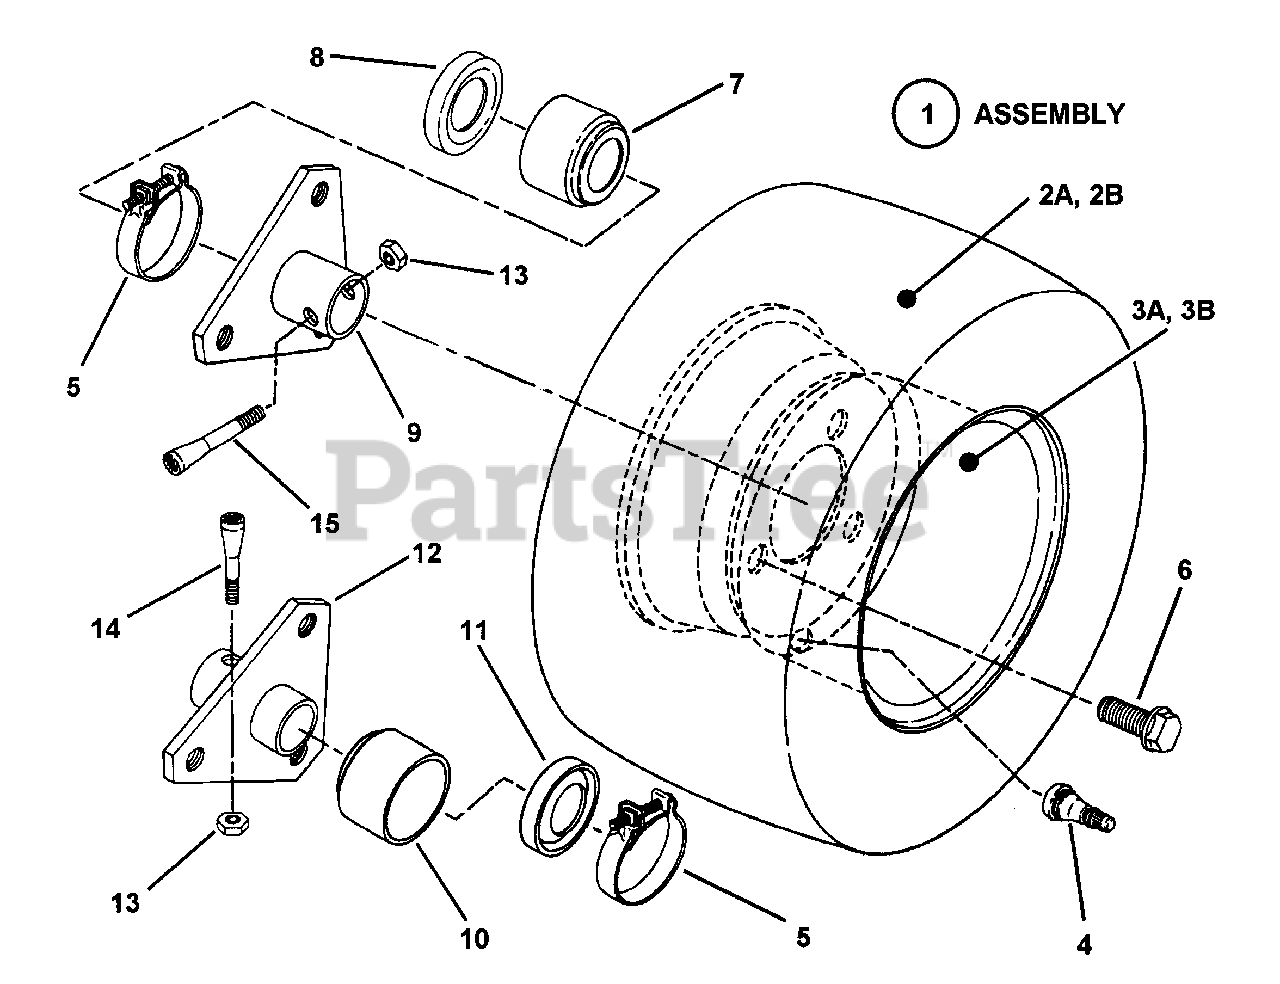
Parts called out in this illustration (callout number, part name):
1	ASSEMBLY, Rear Tire & Rim
2A	TIRE, Wide, 16/6.50 x 8 Turf
2B	TIRE, 4.80/4.00 Turf Saver
3A	RIM, Wide,
3B	RIM, 4.80/4.00 x 8, 3 Lug
4	VALVE, Air (Snap-in)
5	CLAMP
6	BOLT, 1/2-20 x 3/4" Lug
7	CAP, Seal (Right Hand)
8	SEAL, Oil (Right Hand)
9	HUB, Rear Wheel (Right Hand)
10	CAP, 3/4" Hole (Left Hand)
11	SEAL, Oil (Left Hand)
12	HUB, Rear Wheel (Left Hand)
13	NUT, 5/16-24 Hex Center Lock
14	BOLT, 5/16-24 x 1-5/8" Tapered (Left Hand)
15	BOLT, 5/16-24 x 2" Tapered (Right Hand)
